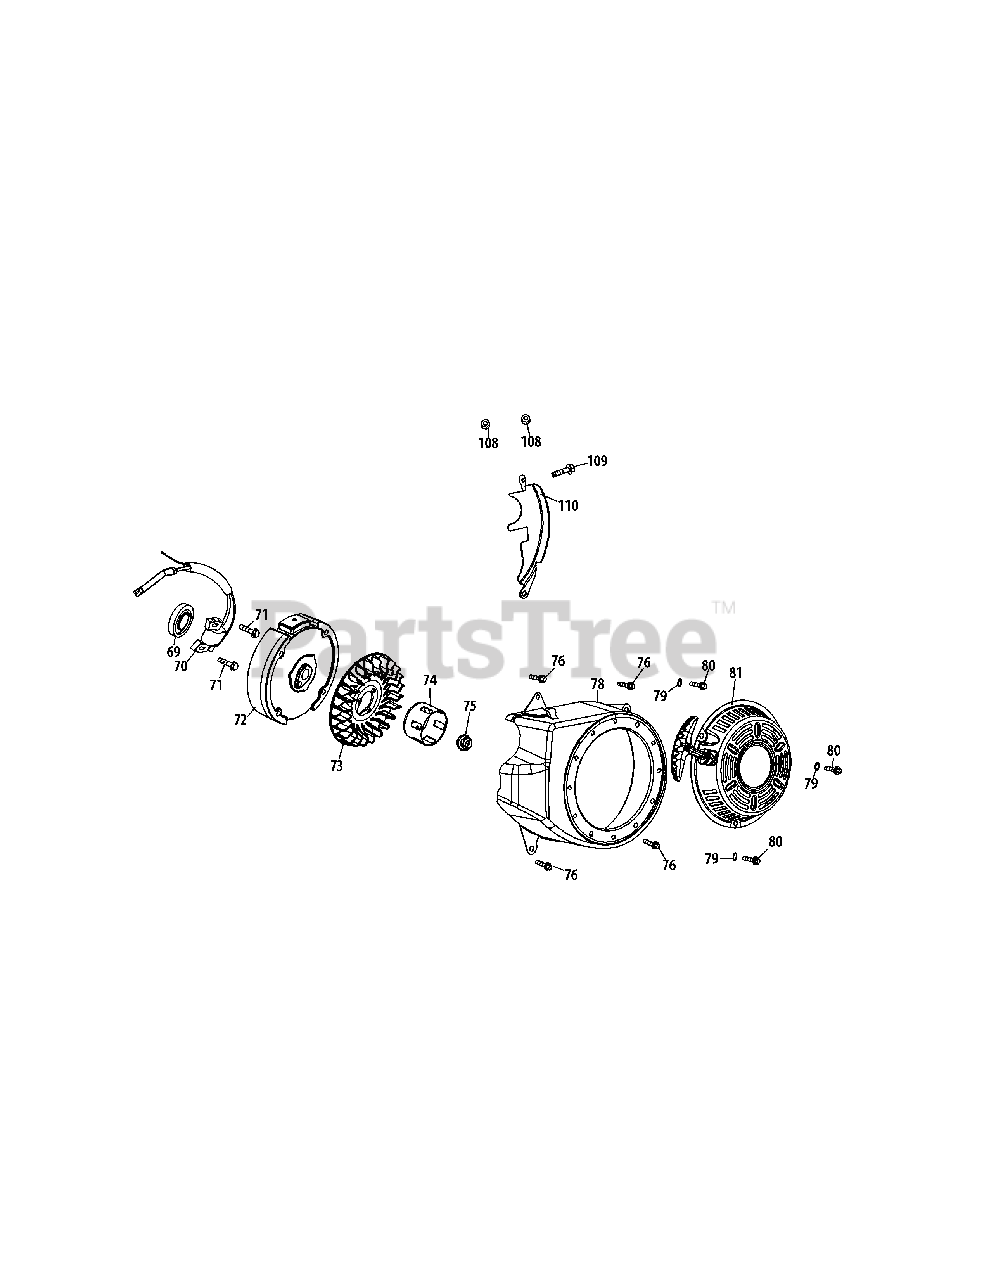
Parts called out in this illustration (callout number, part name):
69	Oil Seal, 25×?41.25×6
70	Ignition Coil Assembly
71	Bolt M6×25
73	Fan - Cooling
74	Starter Cup
75	Nut Special M14×1.5
76	Bolt M6×12
78	Blower Housing
79	Washer, Flat
80	Bolt M6×10
81	Recoil Starter
108	Nut, M6
109	Bolt M6×20
110	Blower Housing Shield
